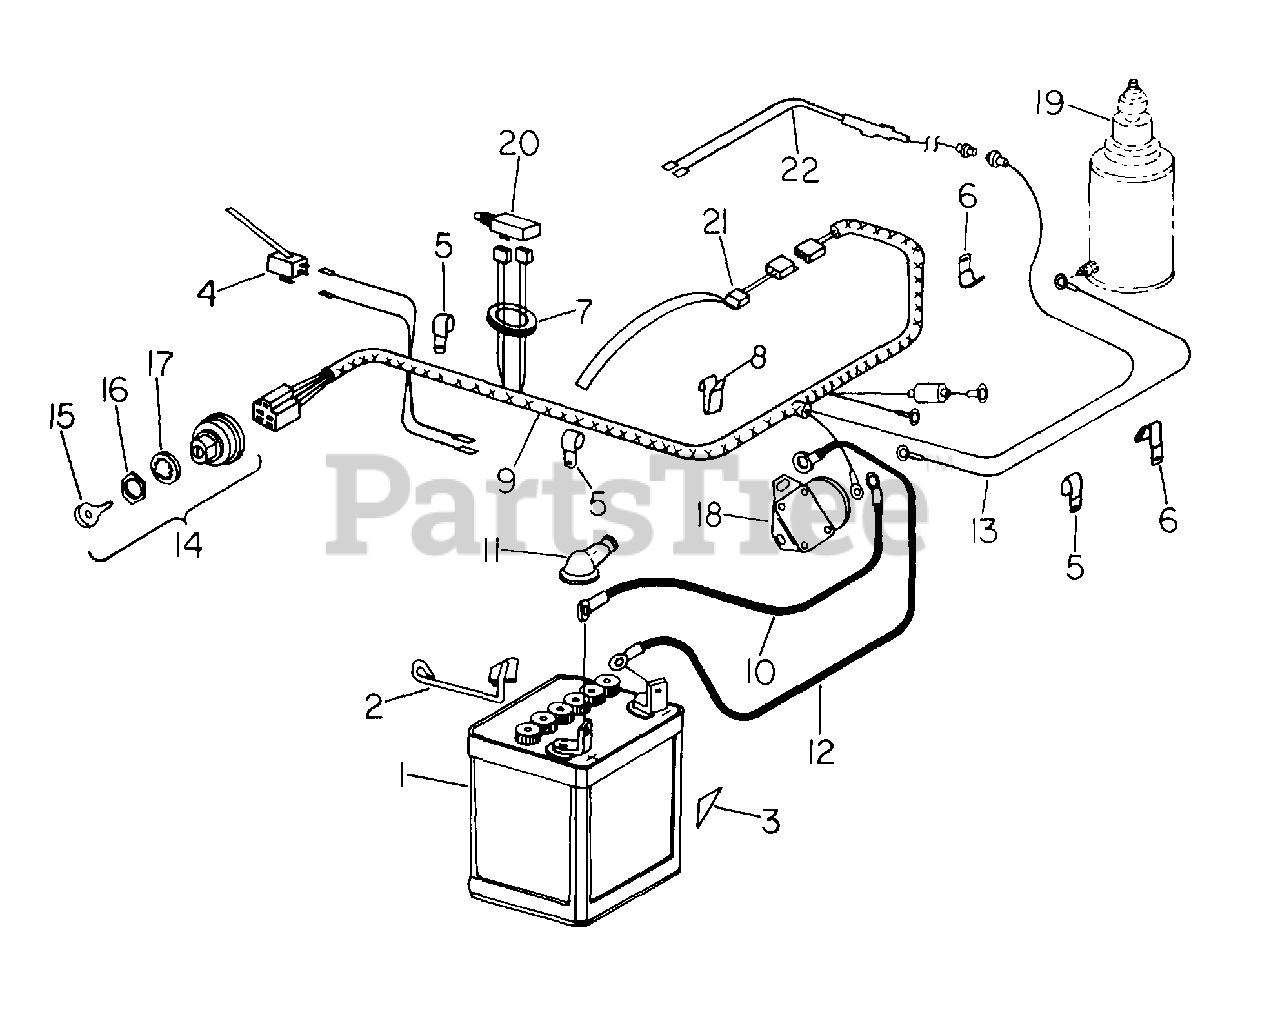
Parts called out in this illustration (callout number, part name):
1	BATTERY, LOW-MAINTENANCE -12 VOLT-
2	CLAMP ASSY, BATTERY
3	PAD, BATTERY
4	SWITCH, REVERSE CUT OUT
6	CLIP, CABLE
8	CLIP, CABLE SPEED
9	HARNESS, CABLE
10	CABLE, BATTERY POSITIVE
11	INSULATOR, BATTERY CABLE
12	CABLE, BATTERY GROUND
13	CABLE, SWITCH TO STARTER
14	SWITCH MAGNETO IGNITION AND STARTING
15	KEY, IGNITION SWITCH
16	NUT, MAGNETO IGNITION KEY MOUNTING
17	WASHER, MAGNETO IGNITION KEY MOUNTING
18	SWITCH, MAGNETIC
19	STARTING MOTOR
20	SWITCH, NEUTRAL STARTING
22	DIODE ASSY, TRI CIRCUIT
